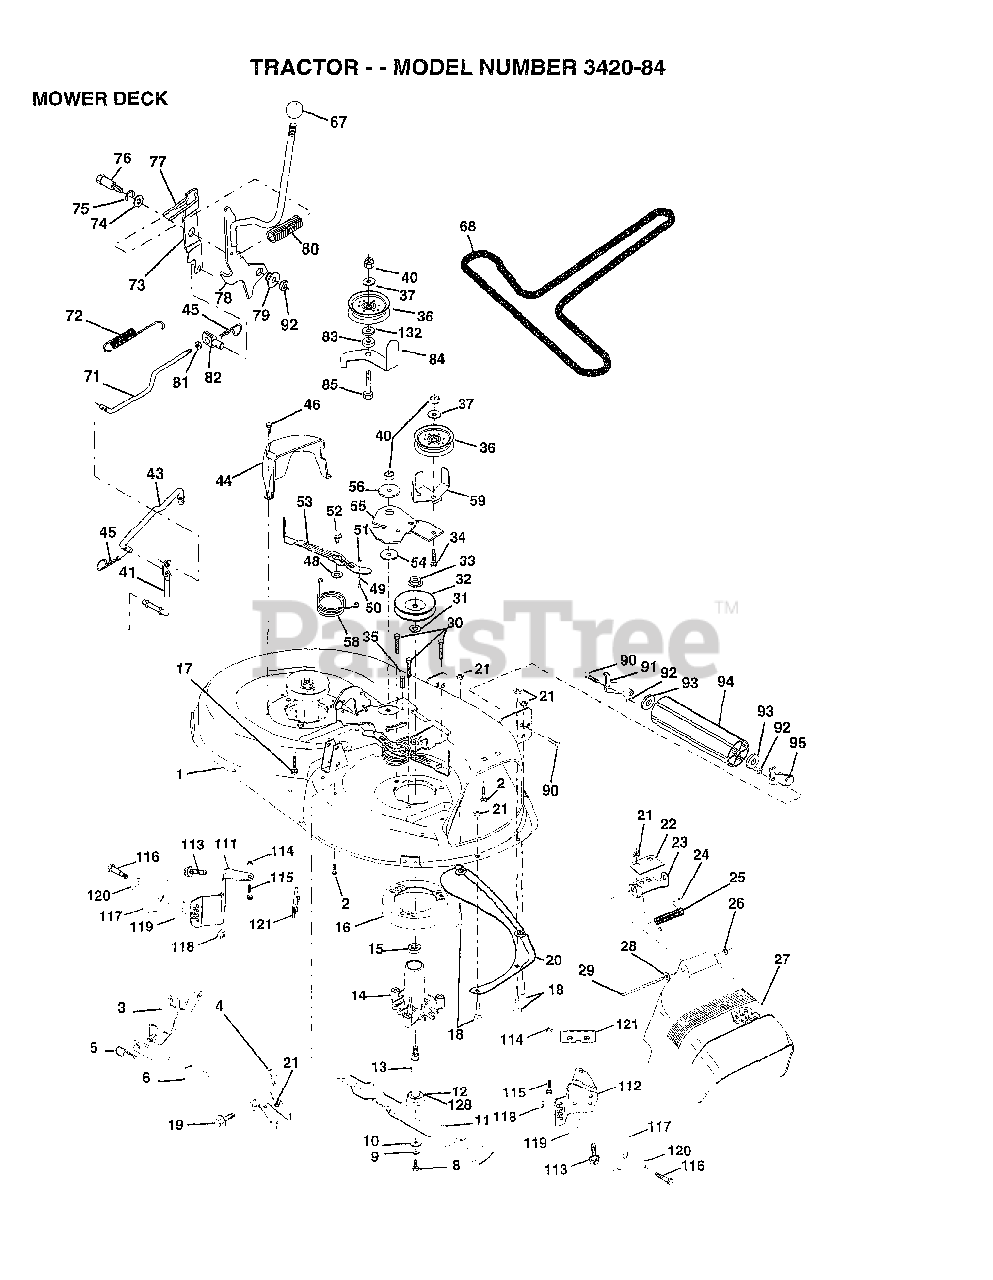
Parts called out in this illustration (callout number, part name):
1	DECK.WELD.42.
2	BOLT
3	BRKT ASM SWAY BAR
4	BRKT DECK SW BAR
8	BLADE BOLT
10	WASHER.HARD.BLADE
11	"BLADE.42"" HIPERF"
12	BEARING.BALL
14	HSG ASM MANDREL
15	BEARING
16	STRIPPER RND MWR
17	BOLT RDHD 3/8-16
18	BOLT
19	BOLT SHD 5/16-18
20	BAFFLE VORTEX 42
22	STIFFENER BRKT
23	DEFLECTOR BRKT
24	CAP-SLEEVE LT
25	SPRING TORSION
27	DEFLECTOR.SHIELD
28	WASHER
29	HINGE ROD
30	"SCREW-THD ROLL,WA"
31	WASHER
32	PULLEY.MANDREL.42
34	BOLT
35	XMAS TREE FASTNER
36	FLAT IDLER PULLEY
37	WASHER
41	PIVOT ROD
43	ROD CLUTCH W/NIBS
44	GUARD MAND LH BLK
46	SCREW.1/4-20X5/8
48	HARD SMALL WASHER
49	ROLLER ASM-CAM
50	SHOULDER BOLT
51	LOCKNUT
52	BOLT.SHLD.5/16-18
53	BRAKE PAD ARM ASM
54	HARDENED WASHER
55	ARM-IDLER
56	SPACER RETAINER
58	SPRING TORSN BRAK
59	GUARD IDLER TUV
68	BELT.V.T-PATH
71	ROD CLUTCH 38/42
72	RETURN SPRING
73	CLUTCH ARM SECOND
74	WASHER
75	RING
76	SHOULDER BOLT
77	SPRING KEEPER
78	LEVERA.ASM.CLUTCH.PRIMARY
79	BUSHING
80	SPRING.CLUTCH.MWR
81	NUT
82	TRUNION ADJ
83	WASHER
84	"KEEPER-BELT,FIXED"
85	BOLT RDHD 3/8-16
90	BOLT
92	NUT
93	WASHER
111	BRACKET.GWHL.LH.
112	BRACKET.GWHL.RH.
113	SCREW
116	BOLT M
117	WHEEL.GAGE.BLK.PL
118	LOCKNUT
119	WASHER
120	WASHER
121	BRACKET.EXTRD.GWL
128	WASHER.FELT.
132	WASHER GT
